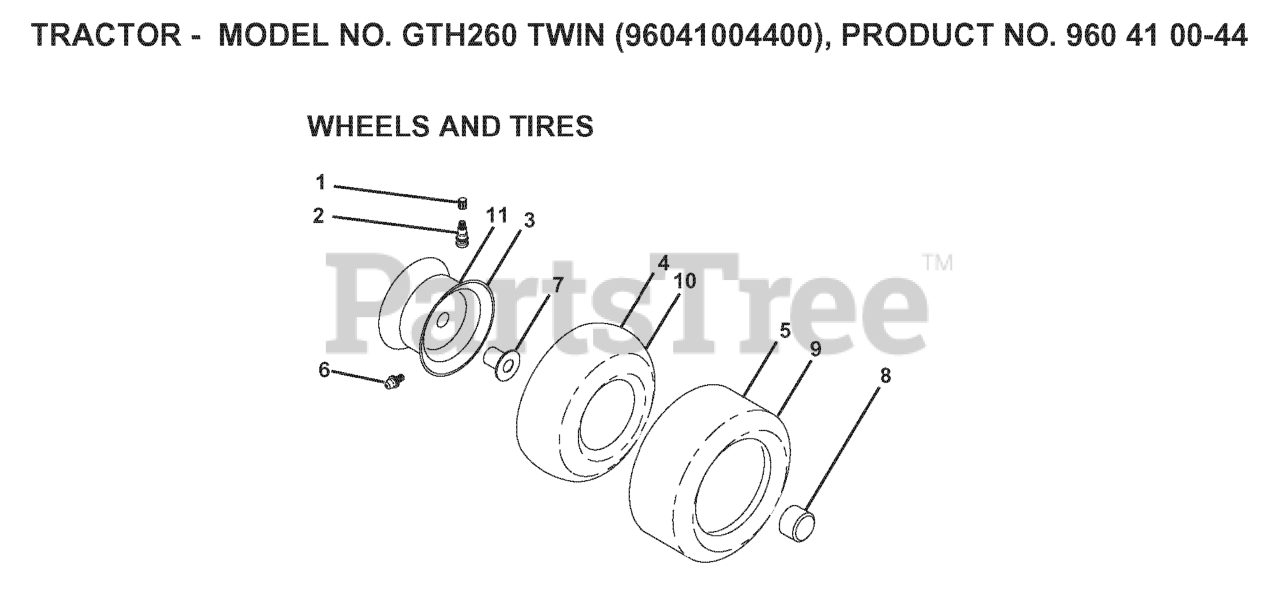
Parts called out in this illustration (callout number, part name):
2	VALVE STEM LT
3	RIM ASSEMBLY, FRONT
4	TUBE.16X6.5/7.5-8
5	TIRE HEAVY DUTY
6	FITTING LT
7	BEARING T
8	CAP, AXLE BLK
9	TIRE HEAVY DUTY
10	TUBE.23X9.5-12
11	RIM.ASM.12X7.REAR.SILVER
